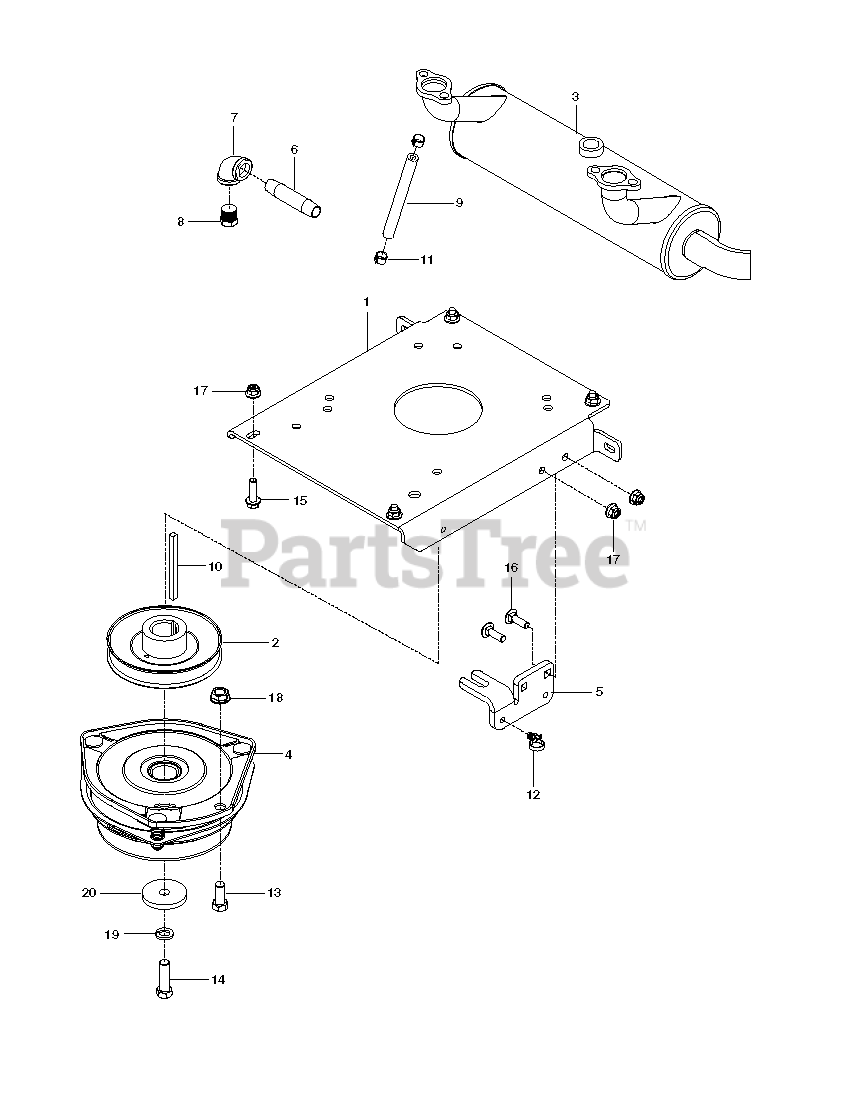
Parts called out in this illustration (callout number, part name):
1	PLATE.ENGINE.BLACK
2	PULLEY, ENGINE
3	MUFFLER.KOH.EFI.W/O2.SENSOR
4	CLUTCH, GT3.5
5	STOP, CLUTCH, OGURA
6	PIPE NIPPLE 3/8 X 3
7	90 DEG.ELBOW 3/8NPT
8	PLUG, DRAIN 3/8 NPTF
9	FUEL LINE 5"
10	KEY, 1/4 SQ X 3.5
11	HOSE CLAMP
12	TIE WRAP, 8-3/8", W/CLIP
13	HCS 7/16-14 X 1 GR 5 ZD
14	CLUTCH BOLT7/16-20X1.5GR5.96HR
15	HHFS 5/16-18 X 1.5 GD 5
16	RHSNB 5/16C X 1
17	5/16-18 NYLOC FLANGE NUT
18	NUT 7/16C WHIZ
19	WASHER 7/16 LOCK
20	BLADE WASHER
